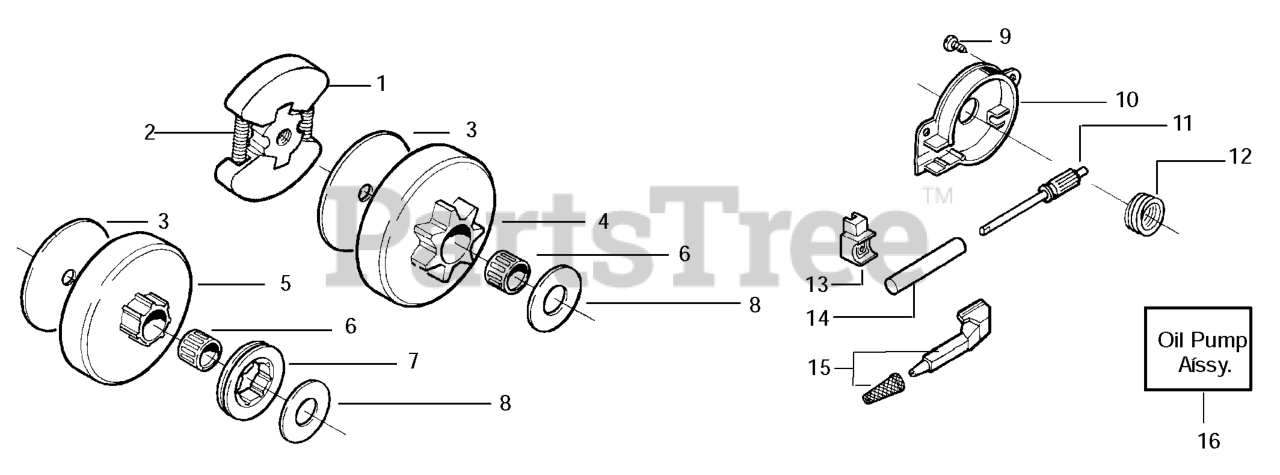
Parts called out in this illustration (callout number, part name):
1	CLUTCH ASSEMBLY
2	CLUTCH SPRING 36/41
3	FRICTION DISC,CLUTCH 36/41
4	SPUR SPRKT .325 7T 36/41
5	CLUTCH DRUM 325 X 7T
6	NEEDLE BEARINGS 36/41
7	RIM .325 7T 36/41
8	THRUST WASHER
10	OIL PUMP HOUSING
11	PLUNGER & GEAR ASSEMBLY
12	OILER GEAR 36/41
13	PRESSURE SEAL,OILER 36/41
14	OIL PUMP BARREL
15	OIL PICKUP
16	OILER ASS'Y 36/41
